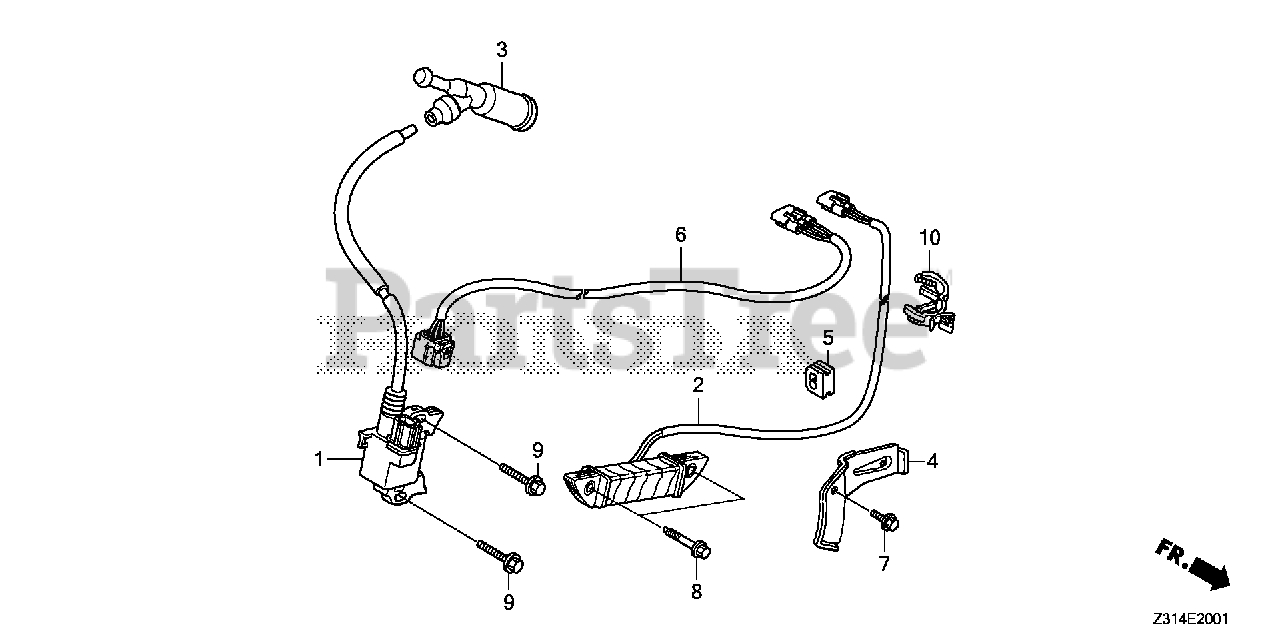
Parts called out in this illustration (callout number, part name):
1	COIL ASSY., IGNITION
1	COIL ASSY., IGNITION (IIDA)
2	COIL ASSY., POWER
3	CAP ASSY., NOISE SUPPRESSOR (NGK Y-EZD)
4	CLAMP, WIRE
5	GROMMET, WIRE
6	WIRE HARNESS ASSY., ENGINE
7	BOLT, FLANGE (6X12) (CT200)
8	BOLT, FLANGE (6X32)
9	BOLT, FLANGE (6X28) (CT200) Use up to Engine SN 1530314.
10	CLIP, WIRE HARNESS
